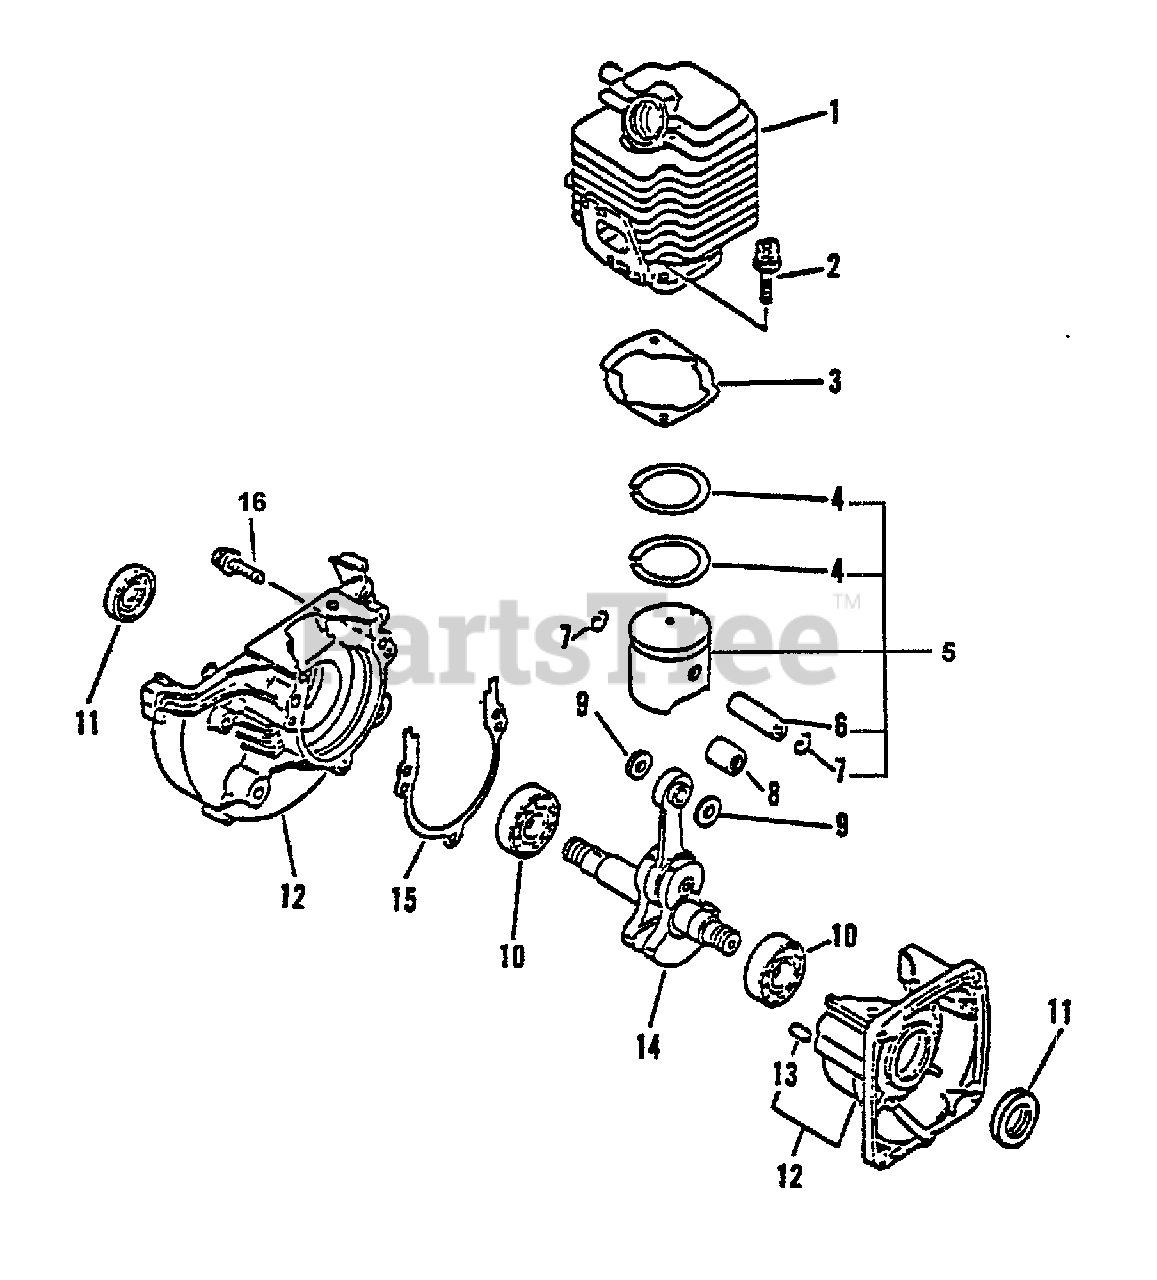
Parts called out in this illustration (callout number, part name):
1	CYLINDER
2	BOLT 5×22
3	GASKET, CYLINDER
4	RING, PISTON
5	PISTON KIT
6	PIN, PISTON 8
7	RING, SNAP
8	BEARING, NEEDLE
9	WASHER, THRUST
10	BEARING, BALL - 6201 C3
11	SEAL, OIL 12
12	CRANKCASE KIT
13	PIN, LOCATING 4
14	CRANKSHAFT
15	GASKET, CRANKCASE
16	BOLT 5×28
